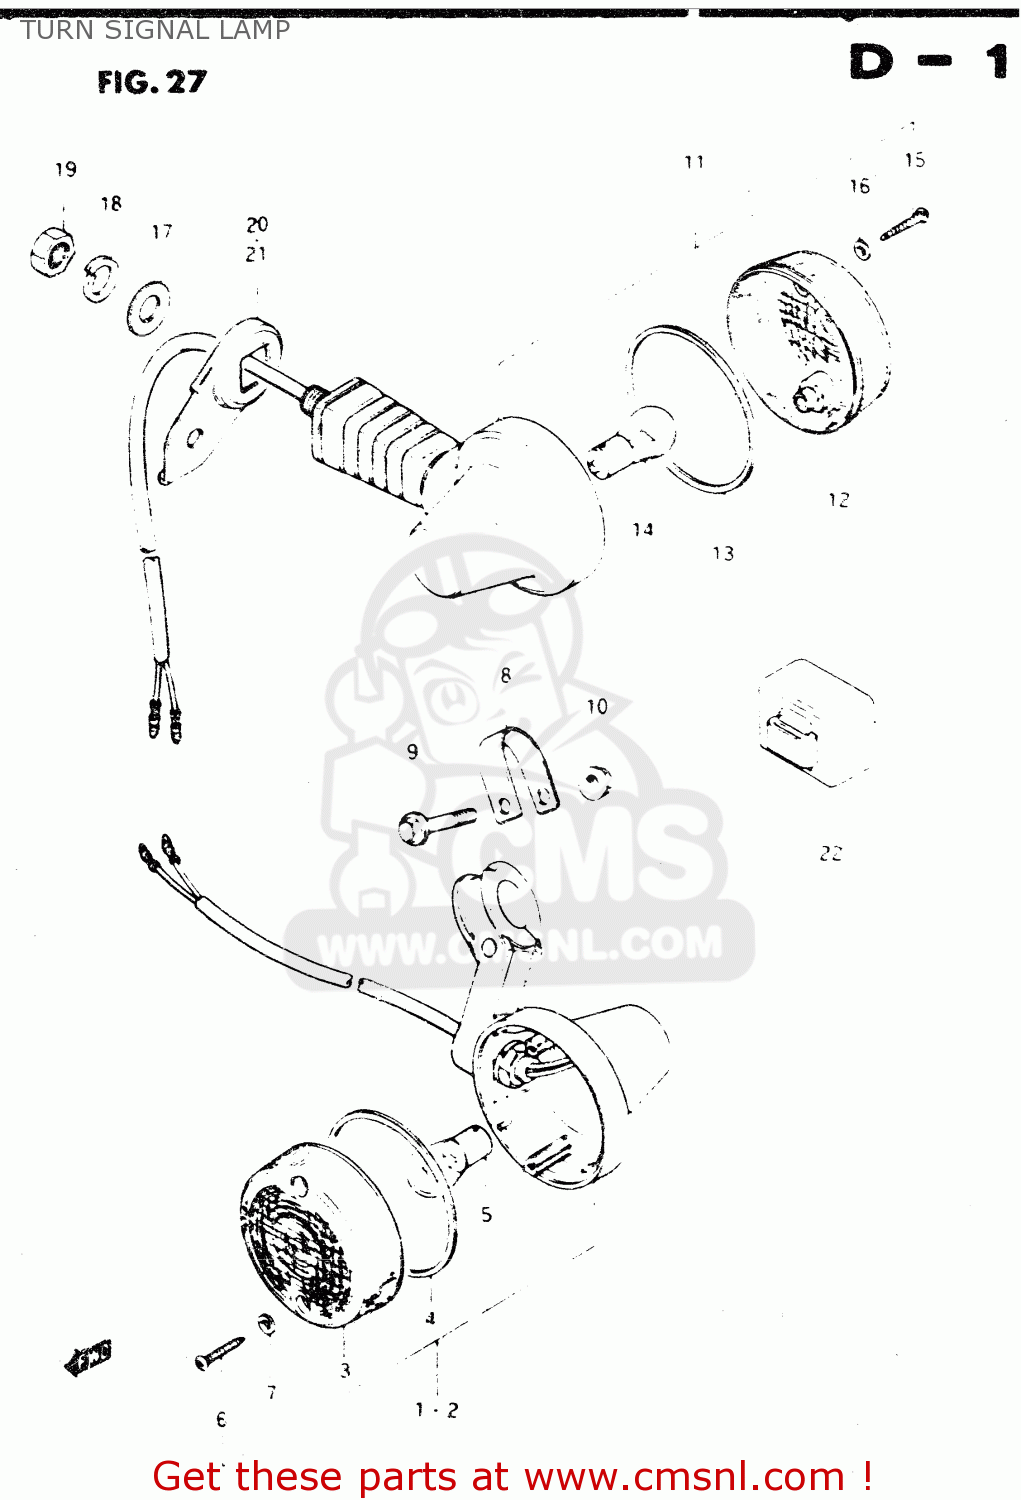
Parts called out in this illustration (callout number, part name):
1	LAMP ASSEMBLY,FRONT TURN SIGNAL
2	LAMP ASSEMBLY,FRONT TURN SIGNAL
3	LENS
4	GASKET (NAS)
5	BULB(6V17W,STANLEY,A4513A)
6	SCREW TAPP.
7	GASKET (NAS)
8	PLATE
9	BOLT 5X42
10	NUT
11	LAMP ASSEMBLY,REAR TURN SIGNAL
12	LENS
13	GASKET (NAS)
14	BULB(6V17W,STANLEY,A4513A)
15	SCREW TAPP.
16	GASKET (NAS)
17	WASHER
18	WASHER,LOCK 12
19	NUT
20	BRACKET,REAR TURN SIGNAL LAMP
21	BRACKET,RR TURNSIGNAL LAMP,L
22	RELAY,TURN SIGNAL
